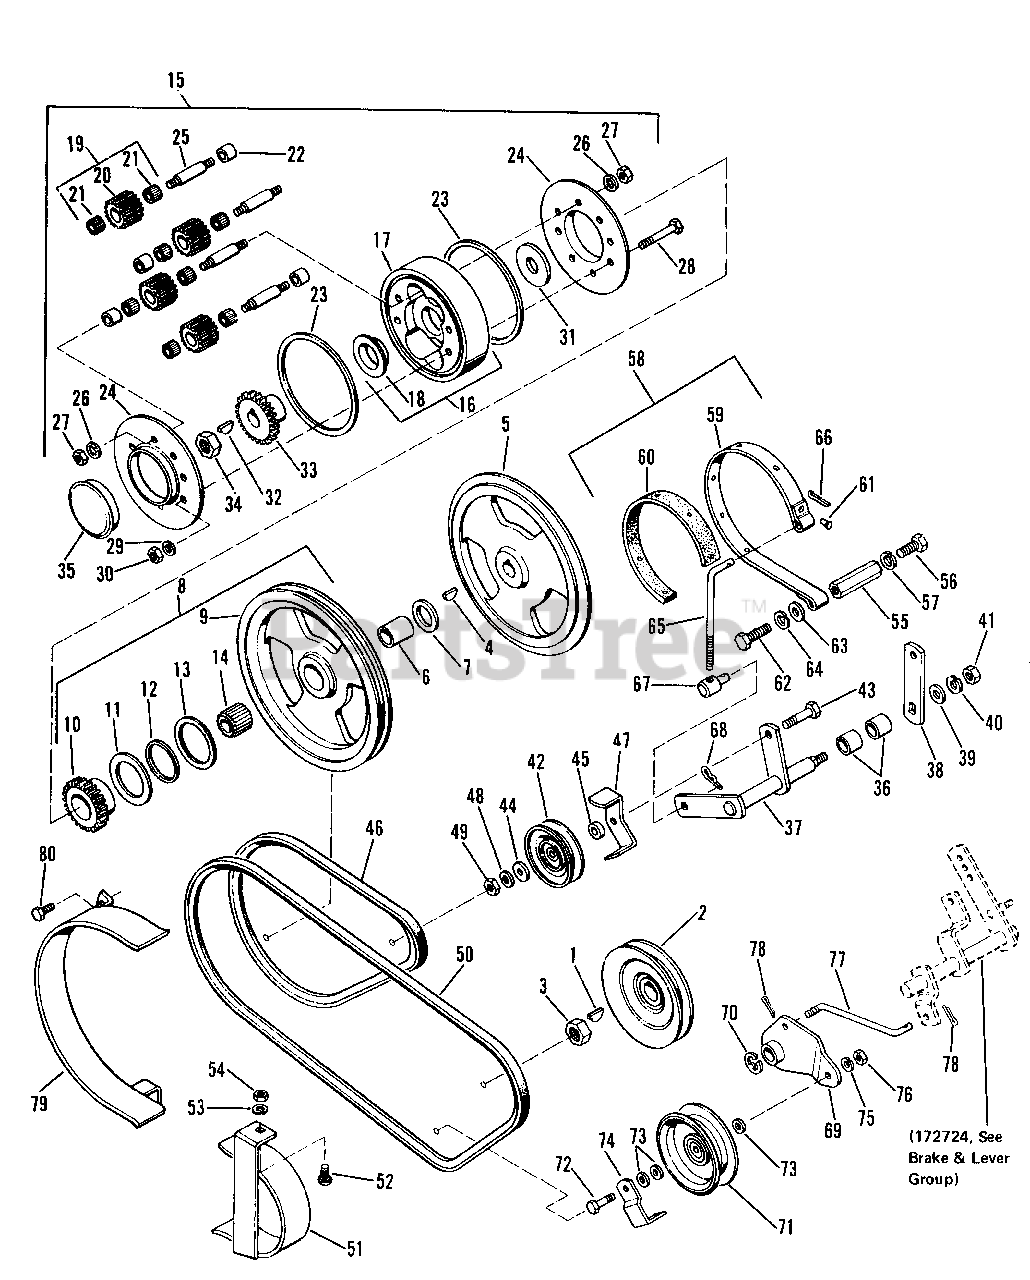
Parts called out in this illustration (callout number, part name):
1	Hi Pro Key 3/16" x 3/4"
3	Jam Hex Nut, 3/4"-16
4	Key, Woodruff No. 9
5	Half Sheave
7	Thrust Bearing
8	Sheave Assembly
10	Gear Differential
14	Bearing, Roller Seal
15	Planetary Assembly
16	Planetary Carrier Sub-Assy.
17	Planetary Carrier
18	Bearing, Flange
19	Pinion Differential Assembly
20	Pinion Differential
21	Bearing, Needle
22	Bearing, Sleeve
24	Differential, Cover
25	Pinion, Pin
26	Lock Washer, Shakeproof
27	Full Hex Nut, 5/16"-18
28	Hex Cap Screw, 5/16"-18 x 2"
29	Lock Washer, 5/16"
30	Full Hex Nut, 5/16"-18
31	Washer, Thrust
32	Hi Pro Key, 3/16" x 3/4"
33	Gear, Differential
34	Jam Hex Nut, 3/4"-16
37	Lever Assembly
39	Plain Washer, 3/8"
40	Lock Washer, 3/8"
41	Full Hex Nut, 3/8"-16
42	Idler Pulley
43	Hex Cap Screw, 3/8"-16 x 1-1/2"
44	Plain Washer, 5/16"
47	Guide Belt
48	Lock Washer, 3/8"
49	Full Hex Nut, 3/8"-16
51	Belt Guard Assembly
52	Carriage Bolt, 3/8"-16 x 3/4"
53	Lock Washer, 3/8"
54	Full Hex Nut, 3/8"-16
55	Brake Anchor
56	Hex Cap Screw, 3/8"-16 x 1"
57	Lock Washer, 3/8"
58	Brake Band Assembly
60	Brake Lining
61	Rivet No. 7 x 1/4"
62	Hex Cap Screw, 3/8"-16 x 1-1/2"
63	Plain Washer, 5/16"
64	Lock Washer, 3/8"
66	Cotter Pin, 3/32" x 3/4"
68	Cotter Pin, 3/32" x 3/4"
69	Idler Lever Assembly
70	Retaining Ring
71	Pulley
72	Hex Cap Screw, 3/8"-16 x 1-1/2"
73	Plain Washer, 5/16"
74	Guide Belt
75	Lock Washer, 3/8"
76	Full Hex Nut, 3/8"- 16
77	Clutch Link
78	Cotter Pin, 3/32" x 3/4"
79	Pulley Guard Assembly
80	Taptite Hex Hd. Washer Screw, 5/16"-18 x 5/8"
